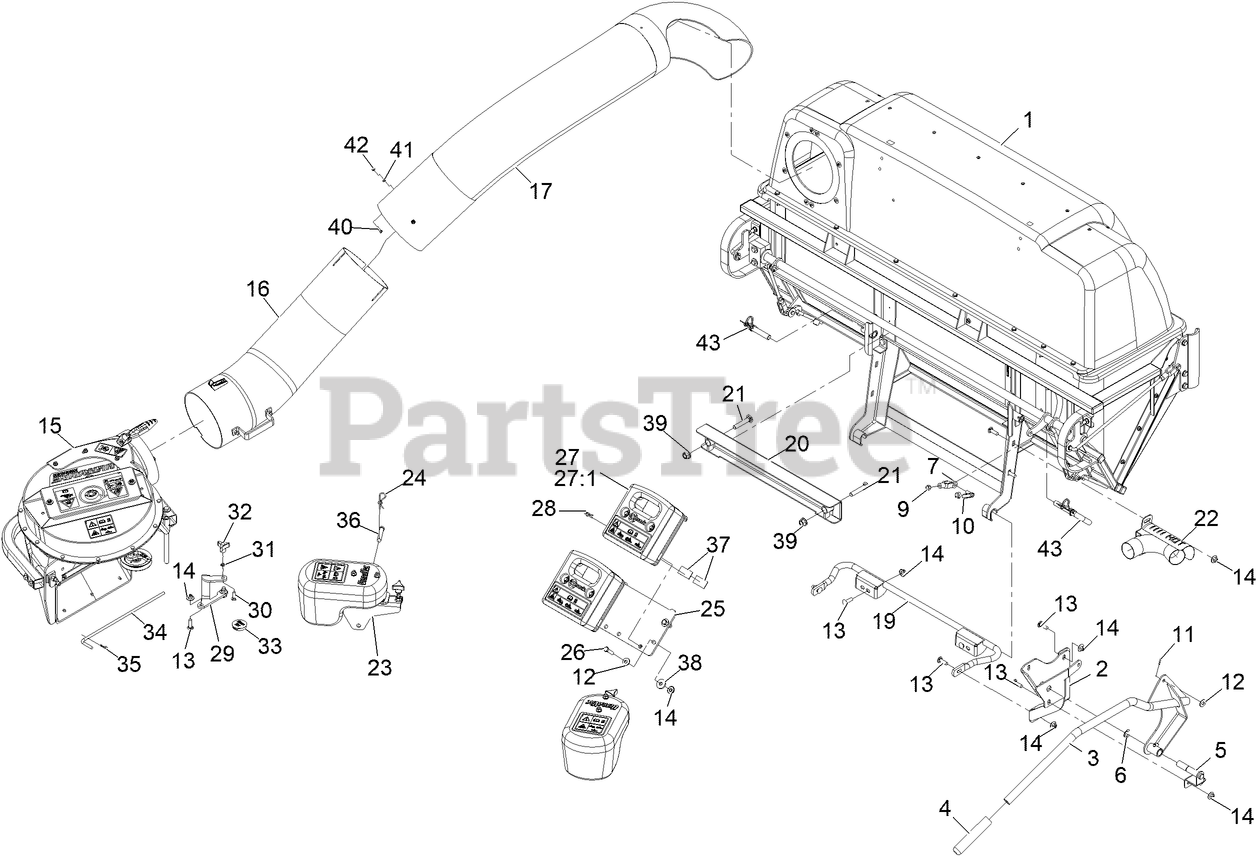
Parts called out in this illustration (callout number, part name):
2	MOUNT-PIVOT
3	WLD,DUMP HANDLE
4	HANDLE-GRIP
5	PIN-HANDLE
7	YOKE-LINKAGE, BRAKE
9	NUT-HEX
10	PIN-SPRING, CLEVIS
11	PIN-COTTER
12	WASHER-FLAT
13	Bolt-Carriage 3/8-16 X 1 1/4
14	Nut-Nyloc 3/8-16 Flg
15	ASM, BLOWER LARGE - SVC ONLY
16	LOWER TUBE ASM
17	TUBE-UPPER
19	MOUNT-BAGGER, LOWER
20	MOUNT-BAGGER, UPPER
21	SCREW-CARR
22	EXHAUST DIVERTER ASM
23	ASM,CASTER WEIGHT
24	PIN-HAIR
25	PLATE,WEIGHT ASM MOUNT
26	SCREW-HH
27	ASM,CAST WEIGHT
27:1	DECAL-WARNING WEIGHT
28	PIN-HAIR
29	BRACKET,BELT COVER
30	BOLT-CARR
31	RING-RETAINING, BOLT
32	KNOB-3 PRONG
33	PLUG, BLACK NYLON 1.75
34	PIN,CHUTE PIVOT
35	PIN-COTTER
36	PIN-CLEVIS
37	PAD-RUBBER
39	Nut-Lock 1/2-13
40	SCREW-HWH
41	WASHER-FLAT
42	NUT-LOCK, NI
43	PIN-MOUNT, BAGGER
